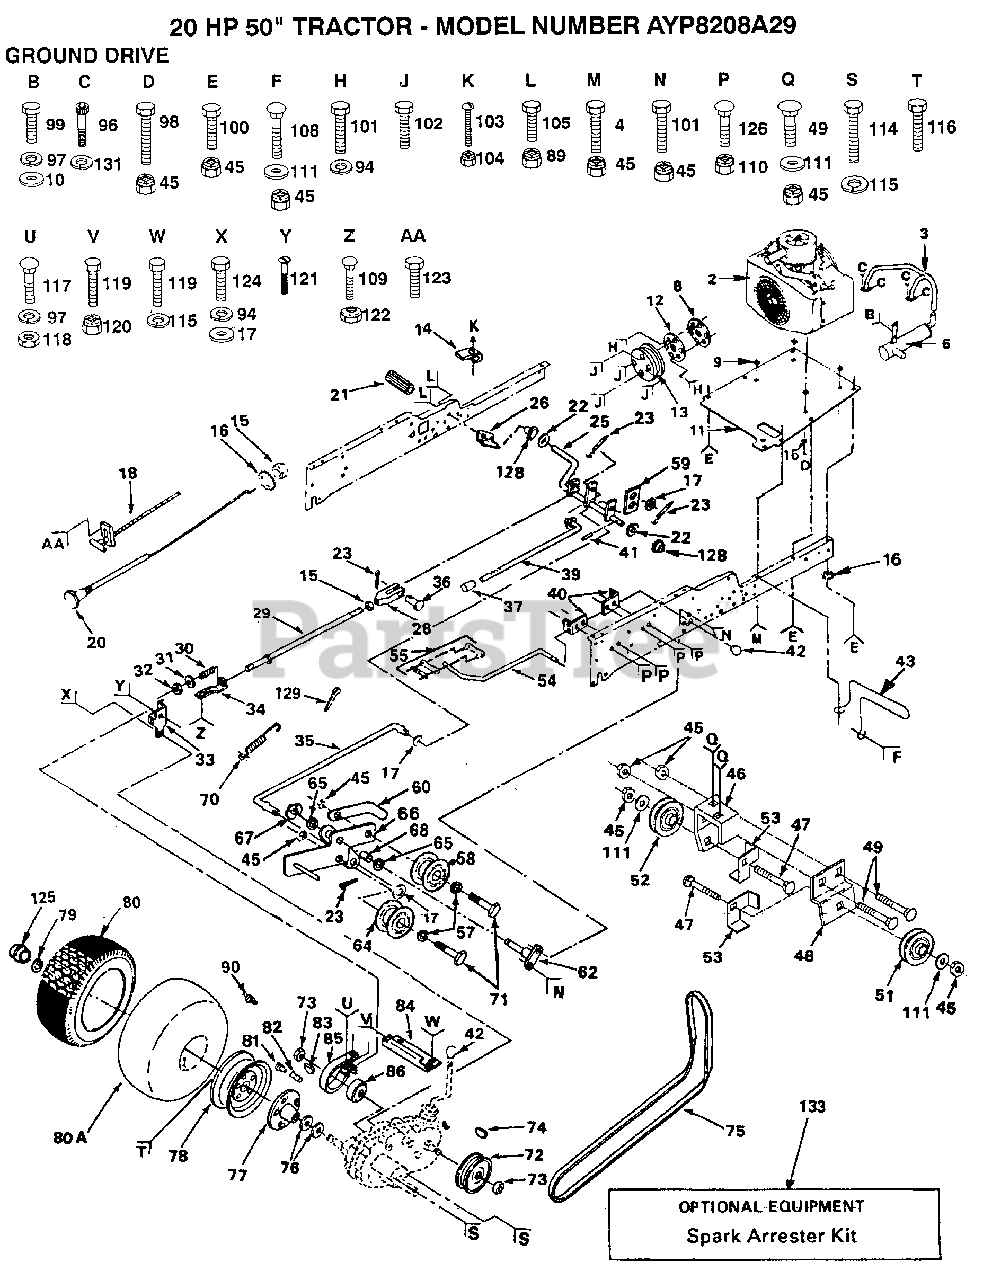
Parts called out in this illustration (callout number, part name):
3	EXHAUST TUBE T
4	"BOLT,HEX"
6	MUFFLER EXHAUST
8	CHAFF GUARD T
11	"ENG. T, BASE"
12	ADAPTER T
14	ACT-SWITCH T
16	LOCKWASHER
17	WASHER
21	PEDAL COVER T
22	WASHER
25	SHAFT ASSY GT
26	BRKT SWITCH GT
28	YOKE GTV
29	BRAKE ROD T
30	SPRING T
31	WASHER
33	BRACKET, BRAKE
34	GUIDE ROD T
35	ROD CLUTCH GTV
36	CLEVIS PIN T
37	PLUNGER CAP T
40	ROD BRACKET GT
41	ROLL PIN STD
42	KNOB
43	GUARD MUFFLER HYT
47	BOLT
48	BRKT IDLER FLAT
49	BOLT
51	IDLER-FLAT T
52	PULLEY V IDLR GTV
53	GUARD BELT
54	ROD SHIFT HI LO
55	CONNECTING LINK
57	WASHER
59	RETAINER SPRING
60	RETAINER BELT
62	BRACKET ASSY GTV
65	WASHER T
66	BRACKET CLUTCH
67	KLIP RING
68	"LY, BEARING"
70	SPRING EXT CLUTCH
72	PULLEY GT
73	NUT STD
75	BELT-V.98.5.GD.DV
76	WASHER T
79	KLIP RING
80A	TUBE.23X8/10-12
81	VALVE CAP
82	VALVE STEM LT
85	BRAKE BAND ASM
86	BRAKE DRUM T
90	ZERK FITTING M
94	LOCKWASHER
96	SCREW
97	LOCKWASHER
101	BOLT
102	SCREW
103	SCREW
105	BOLT LT
108	BOLT.3/8-14X1.25
111	WASHER GT
114	BOLT
115	LOCKWASHER
117	BOLT T
119	BOLT
120	NUT GTV
121	SCREW
123	SCREW LT
125	CAP-HUB GT
126	BOLT
128	NYLINER T
129	COTTER PIN
133	SPARK ARREST KIT
